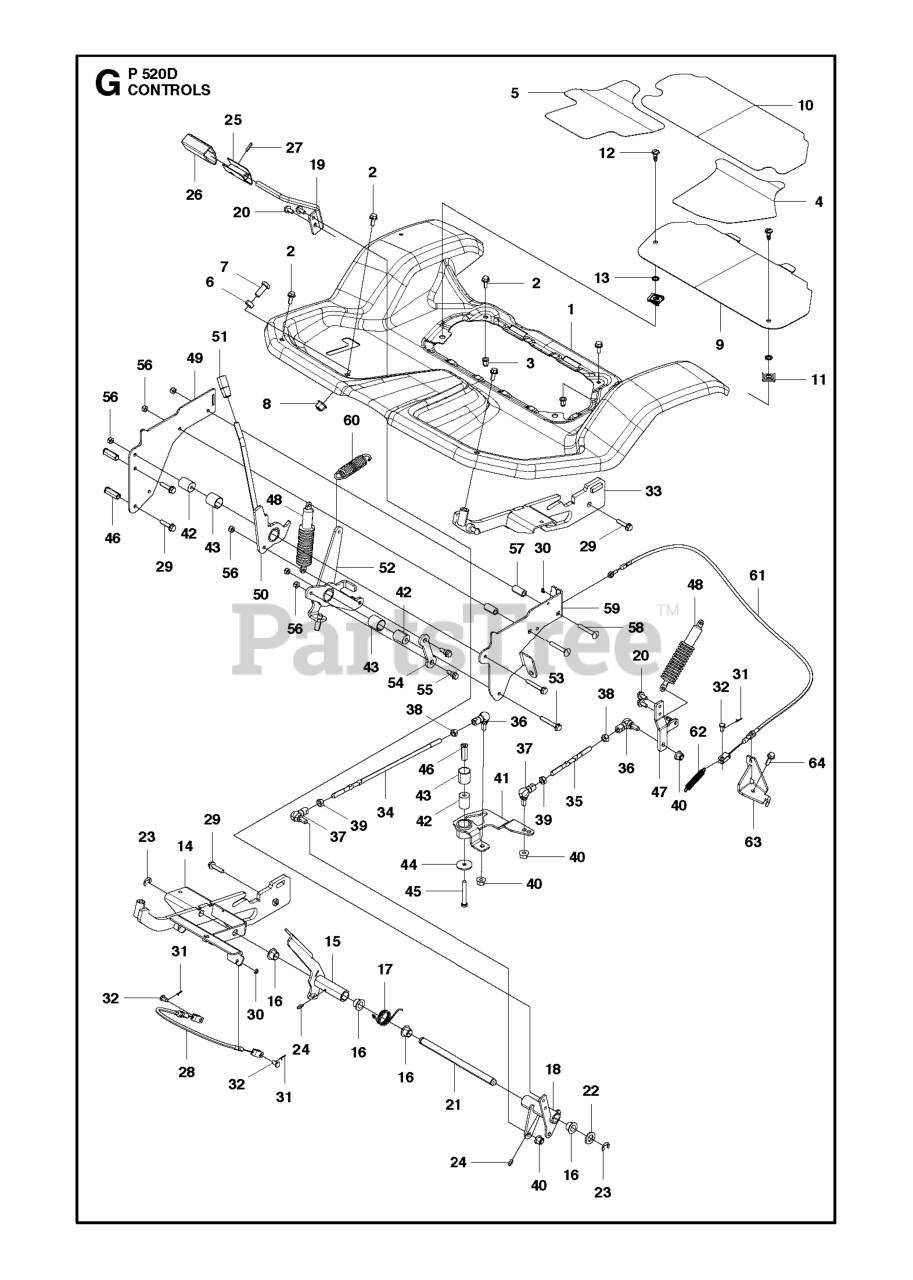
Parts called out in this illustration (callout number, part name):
7	Hex Head Capscrew, M12 X 1.75 X 30 DIN933ZP
16	BUSHING
24	GREASE NIPPLE
26	PEDAL RUBBER
29	SCREW EHHFM
31	Cotter Pin
32	Clevis Pin
39	NUT
43	BUSHING
48	SHOCK ABSORBER
53	SCREW EHHFM
56	LOCKNUT M8
64	BOLT
